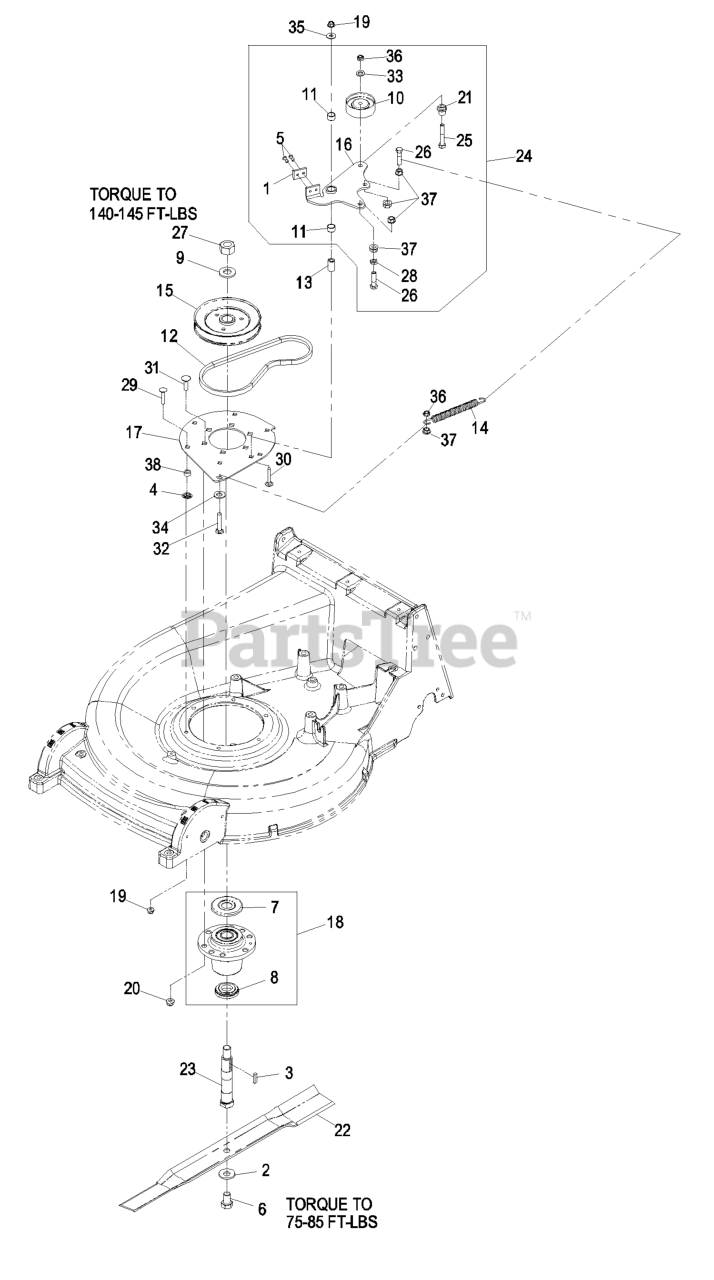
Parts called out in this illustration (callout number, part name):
1	PAD-BRAKE
2	WASHER-SPRING
3	KEY-RECTANGLE
4	RING-RETAINING
5	RIVET-POP
6	SCREW-CAP
7	GUARD-BEARING, TOP
8	SPACER-GUARD, BOTTOM
10	PULLEY-IDLER
11	BEARING
13	BUSHING-ARM, IDLER
14	SPRING-BRAKE
15	SHEAVE-SPINDLE
16	ARM-IDLER
17	PLATE-ADAPTER, HOUSING
18	KIT, CUTTER HOUSING
19	NUT-HF, NI
20	NUT-HF, NI
21	BUSHING-LATCH, SEAT
23	SHAFT-SPINDLE
24	ASM,IDLER ARM
25	SCREW-HH
26	SCREW-HH
28	NUT-JAM
29	BOLT-CARR
30	BOLT-CAR
31	Bolt-Carriage 3/8-16 X 1 1/4
32	SCREW-HH
33	WASHER-FLAT
34	WASHER-FLAT
35	WASHER-FLAT
37	NUT-HHF, WHIZ
38	SPACER
39	ASM,CUTTER HOUSING COMPLE
